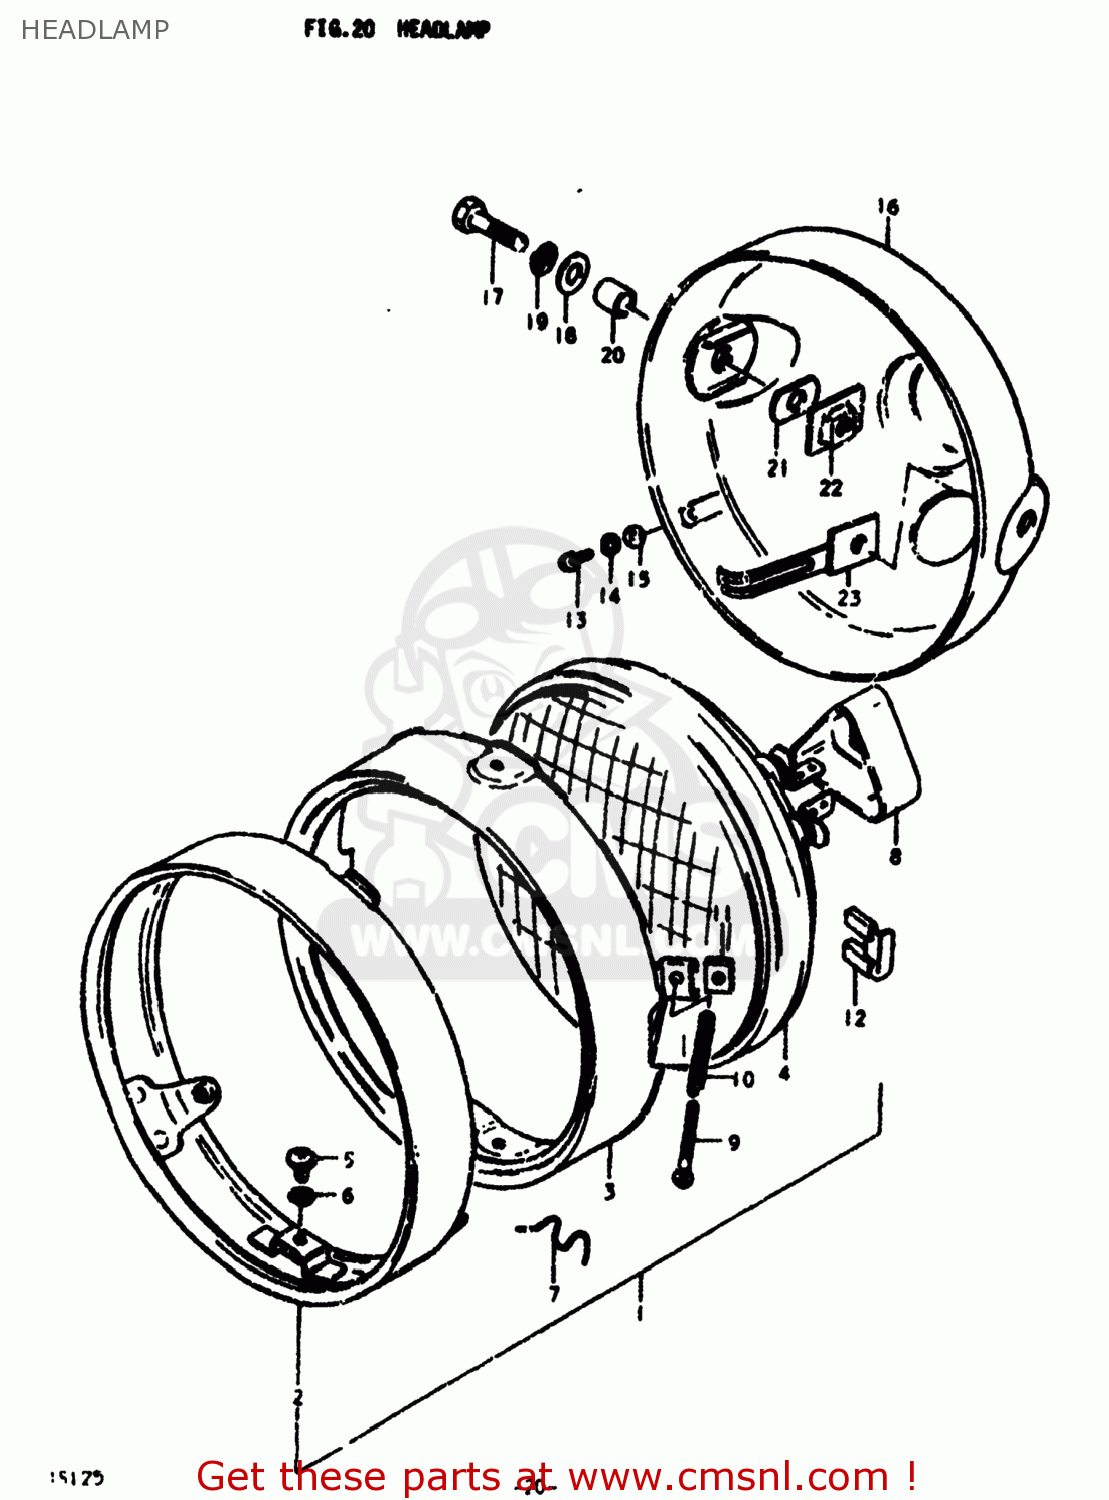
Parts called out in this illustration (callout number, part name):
1	LAMP ASSEMBLY,HEAD
2	RIM,HEADLAMP
3	RETAINER
4	LAMP UNIT
5	SCREW
6	LOCK WASHER
7	SPRING,HEAD LAMP UNIT
8	COVER
9	SCREW
10	SPRING,HEADLAMP ADJUST
11	NUT
12	COVER, FITING
13	SCREW
14	LOCK WASHER
15	WASHER
16	HOUSING,HEADLAMP
17	BOLT
18	WASHER
19	LOCK WASHER
20	SPACER (8.8X12X7)
21	CUSHION
22	PLATE,HEADLAMP HOUSING
23	PLATE,HEADLAMP HOUSING
